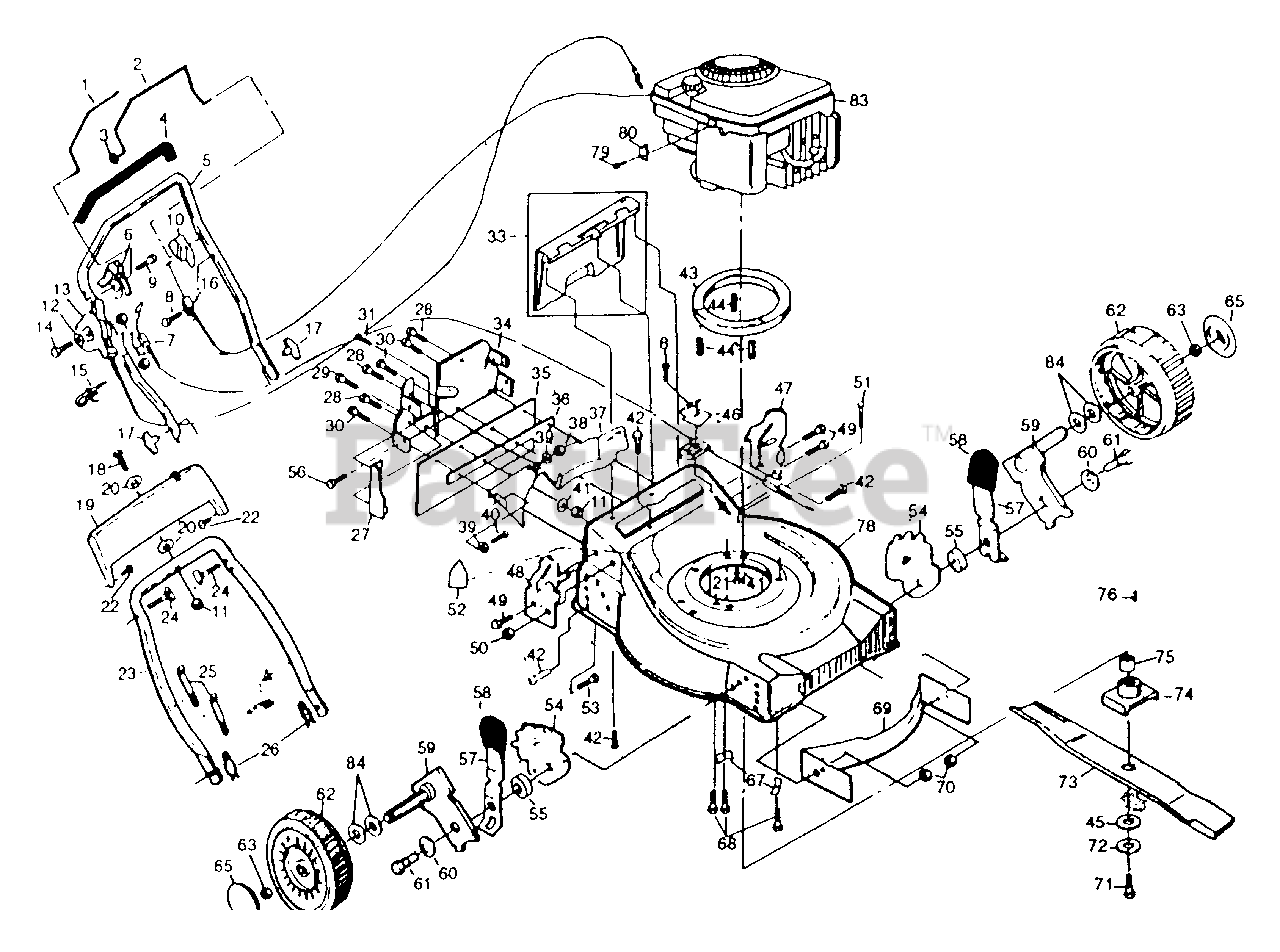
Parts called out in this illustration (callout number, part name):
1	Drive Bar
2	Engine Control Bar
3	Flat Washer
4	Handle Grip
5	Upper Handle
6	Drive Control Actuator
7	Drive Cable Assembly
8	Thread Rolling Screw # 10-24 x 3/4
9	Self-tapping Screw # 10-24 x 5/8
10	Zone Control Actuator
11	Locknut 1/4-20
13	Throttle Control
14	Machine Screw 1/4-20 x 2-1/8
15	Rope Guide
16	Engine Zone Control Cable
17	Handle Knob
18	Hex Washer Head Machine 1/4-20 x 1-1/2
19	Trim Plate Asm
20	Flat Washer 1/4
21	Locknut 1/4-20
22	Self-tapping Screw # 10-24 x 5/8
23	Lower Handle
24	Handle Bolt 5/16-18 x 1-3/4
25	Wire Ties
26	Hairpin Cotter
27	Side Baffle
28	Pop Rivet .156 x .415
29	Hex Head Screw 1/4-20 x 3/4
30	Hex Tapping Screw 1/4-20 x 1/2
31	Hex Washer Head Machine Screw # 10-24 x 9/16
33	Rear Door Kit
34	Back Plate
35	Rear Skirt
36	Backing Strip
37	Rear Baffle
39	Flat Washer
40	Hex Washer Head Tapping Screw x 10-24 x 1/2
42	Hex Tapping Screw 1/4-20 x 1/2
43	Engine Spacer
44	Engine Bushing
46	Bracket Cover
47	Handle Bracket Assembly (Left)
48	Handle Bracket Assembly (Right)
49	Thread Cutting Screw 5/16-18 x 3/4
50	Locknut 5/16-18
51	Carriage Bolt 1/4-20 x 1/2
52	Danger Decal
53	Carriage Bolt 5/16-18 x 5/8
54	Wheel Adjusting Bracket
55	Spacer
57	Selector Spring
58	Selector Knob
59	Axle Arm Assembly
60	Belleville Washer
61	Shoulder Bolt 3/8-16
62	Wheel & Tire Assembly 8.0 x 2.0
63	Nut
67	Engine Washer
68	Hex Head Thread Rolling Screw 3/8-16 x 2
69	Front Baffle
70	Locknut 3/8-16
71	Hex Head Machine Screw Gr.8
72	Helical Washer 3/8
74	Blade Adapter
76	Square Key #HP-505
78	Lawn Mower Housing
79	Thread Rolling Screw # 10-32 x 5/8
80	Cable Clamp
83	Engine - Briggs & Stratton
84	Wave Washer
